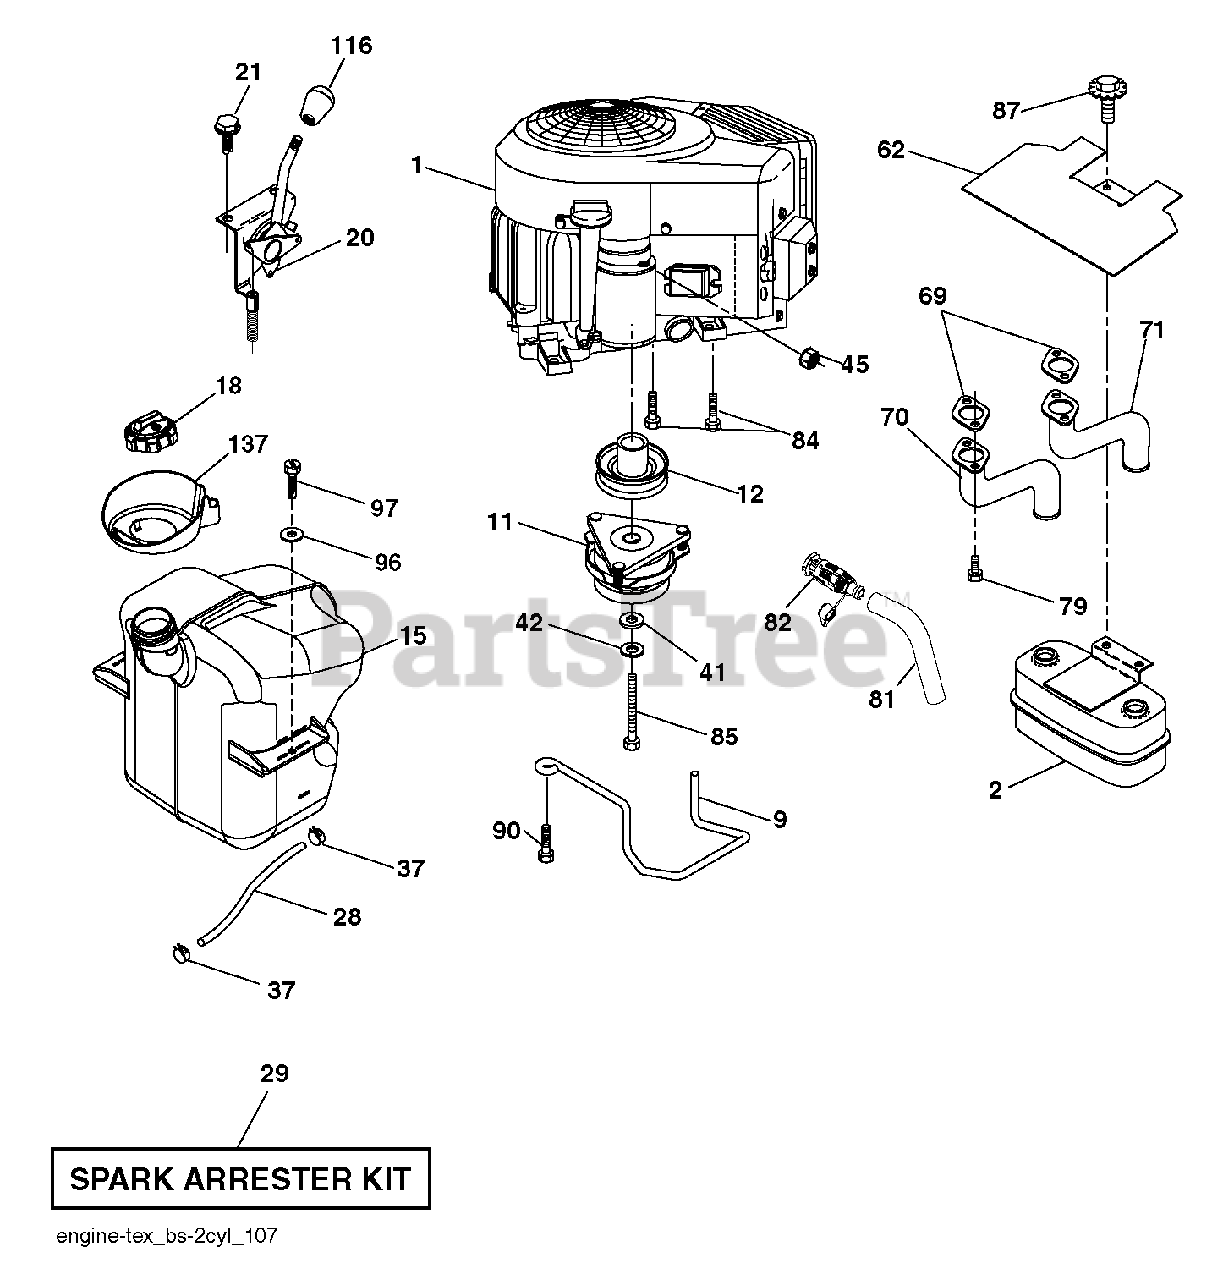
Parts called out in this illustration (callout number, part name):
2	MUFFLER.ASM.TWN.EXTNDED.DFLCTR
9	KEEPER BELT ENGINE
11	CLUTCH.ELECTRIC.LT.48"*
12	PULLEY.ENGINE.TUFFTORQ
15	FUEL TANK TANK. ASSEMBLY. EXTE
18	CAP.ASM.FUEL.2.25"TOP.TURN
20	CONTROL THROTTLE/CHOKE
21	SCREW.#10 X 0.750.BOS
28	LINE.FUEL.20
29	KIT.SPARK ARRESTOR 794945 B&S
37	HOSE CLAMP
42	LOCKWASHER
45	NUT
62	SHIELD.HEAT.MUFFLER
69	GASKET.MUFFLER
70	EXHAUST.TUBE.LH.BS/TWIN
71	EXHAUST.TUBE.RH.B&S.TWIN.INTEK
79	SCREW.SOCKET.HEAD.5/16-18
81	TUBE, DRAIN OIL ASM.
82	VALUE.OIL.DRAIN
84	SCREW.3/8-16
85	BOLT HEX 7/16-20X4-1/4"
87	BOLT, 5/16-18 X 1 3/4
90	SCREW 3/8-16X1
97	SCREW HEXWSHR 1/4-20X3/4
116	KNOB - SHIFT
